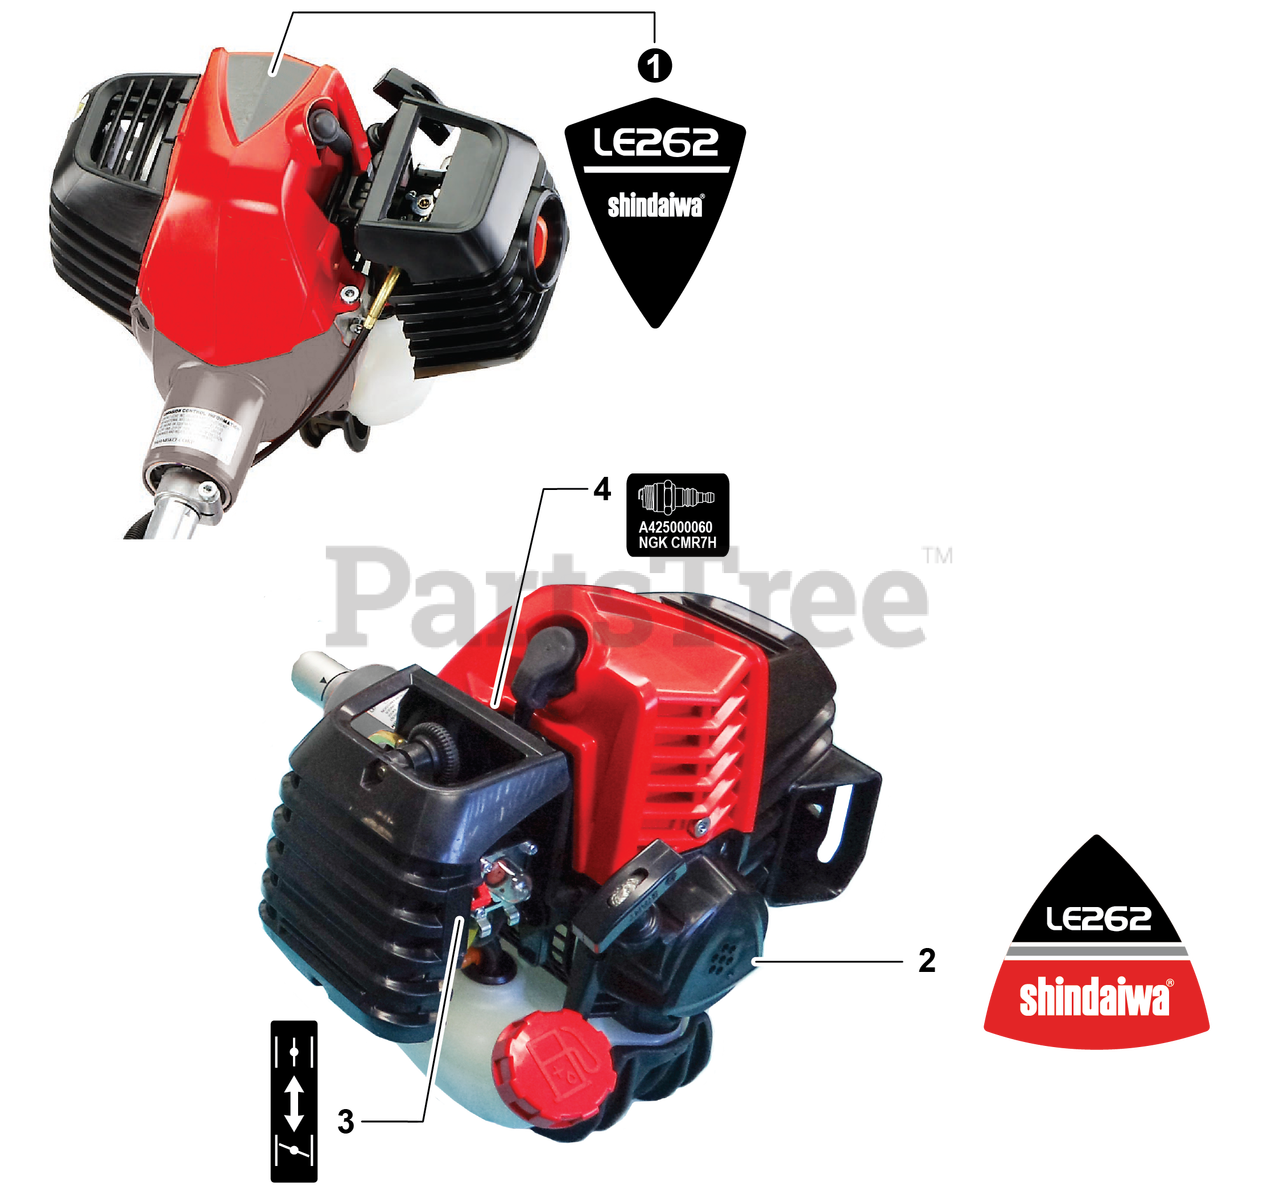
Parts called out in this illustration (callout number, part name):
1	LABEL - MODEL LE262
2	LABEL, RECOIL STARTER
3	LABEL, CHOKE
4	LABEL, SPARK PLUG - CMR7H
